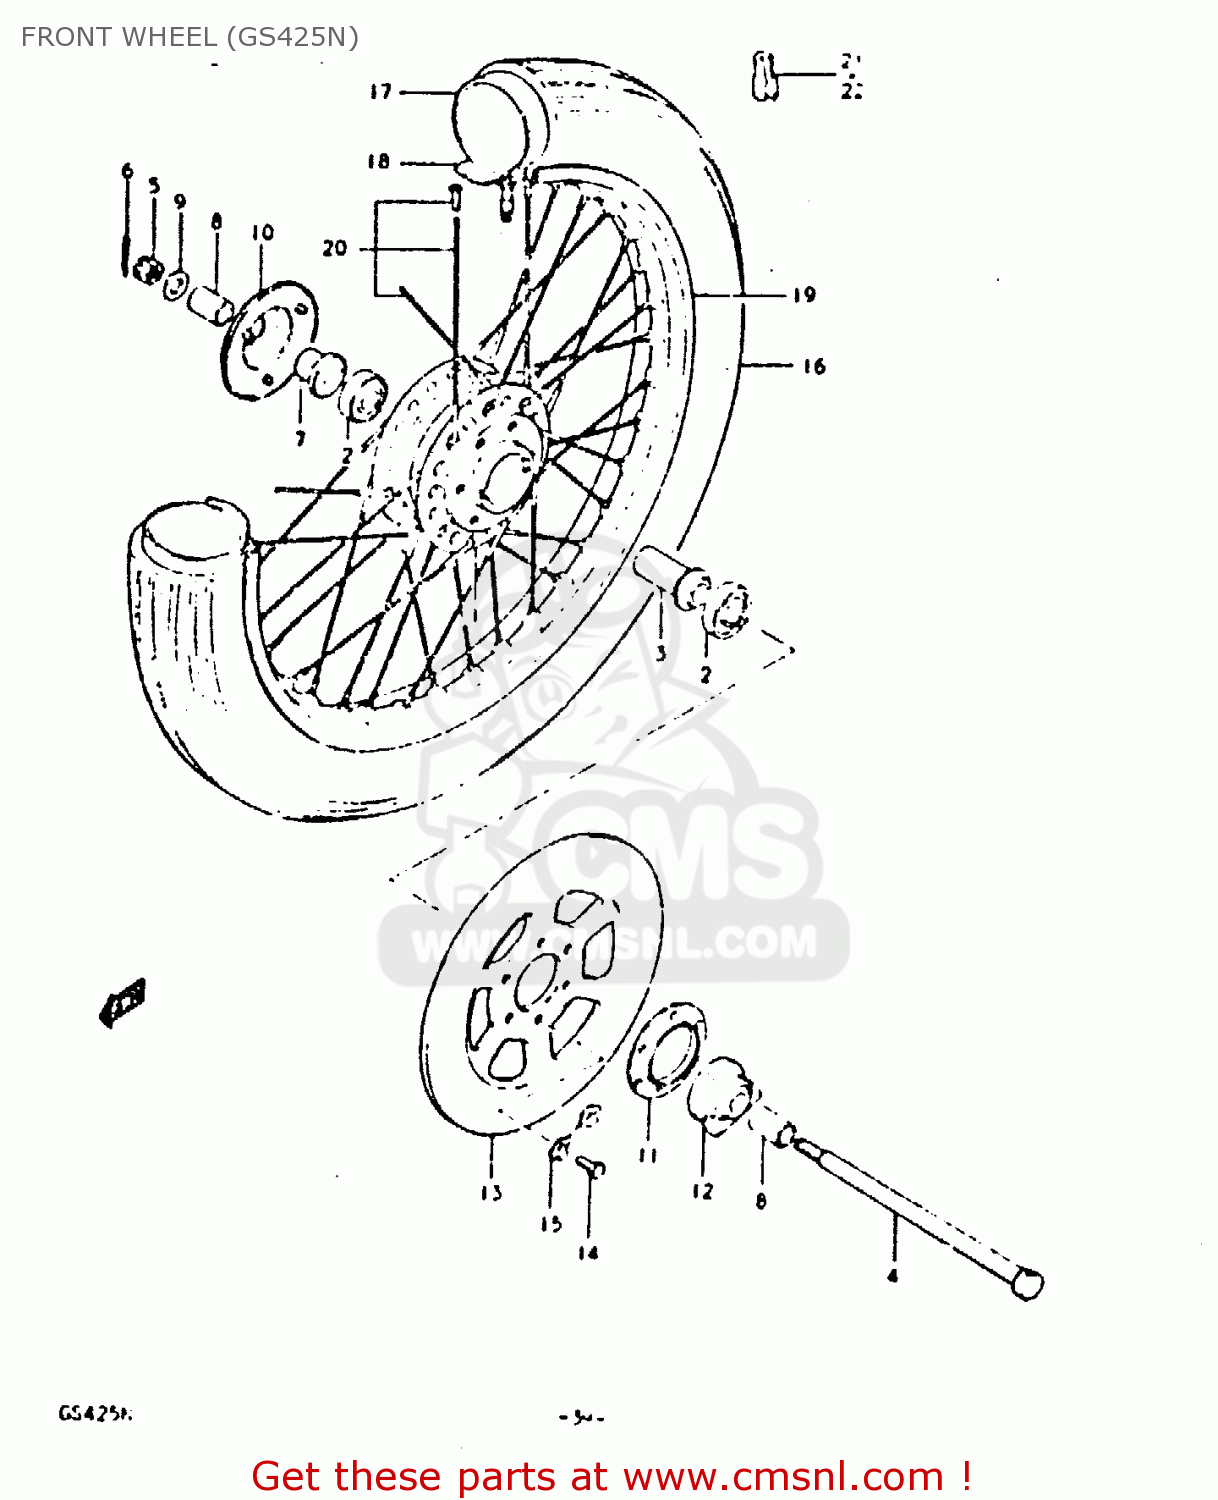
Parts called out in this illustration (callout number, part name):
1	DRUM,FRONT HUB
2	BEARING
3	SPACER,FR HUB BEARING
4	AXLE,FRONT
5	NUT 12MM
6	COTTER PIN
7	SPACER,FR AXLE,R
8	SPACER(15X22X30)
9	WASHER
10	COVER,FR HUB,R
11	DUST SEAL,SPEEDOMETER GEAR BOX
12	BOX ASSY,SPEEDOMETER GEAR
13	DISC,REAR BRAKE
14	BOLT(8X25)
15	WASHER
16	TIRE,FRONT
17	TUBE,INNER
18	PROTECTOR,INNER TUBE
19	RIM,FR WHEEL
20	SPOKE SET,FRONT
21	BALANCER,WHEEL (B)
22	BALANCER,WHEEL (30G)
